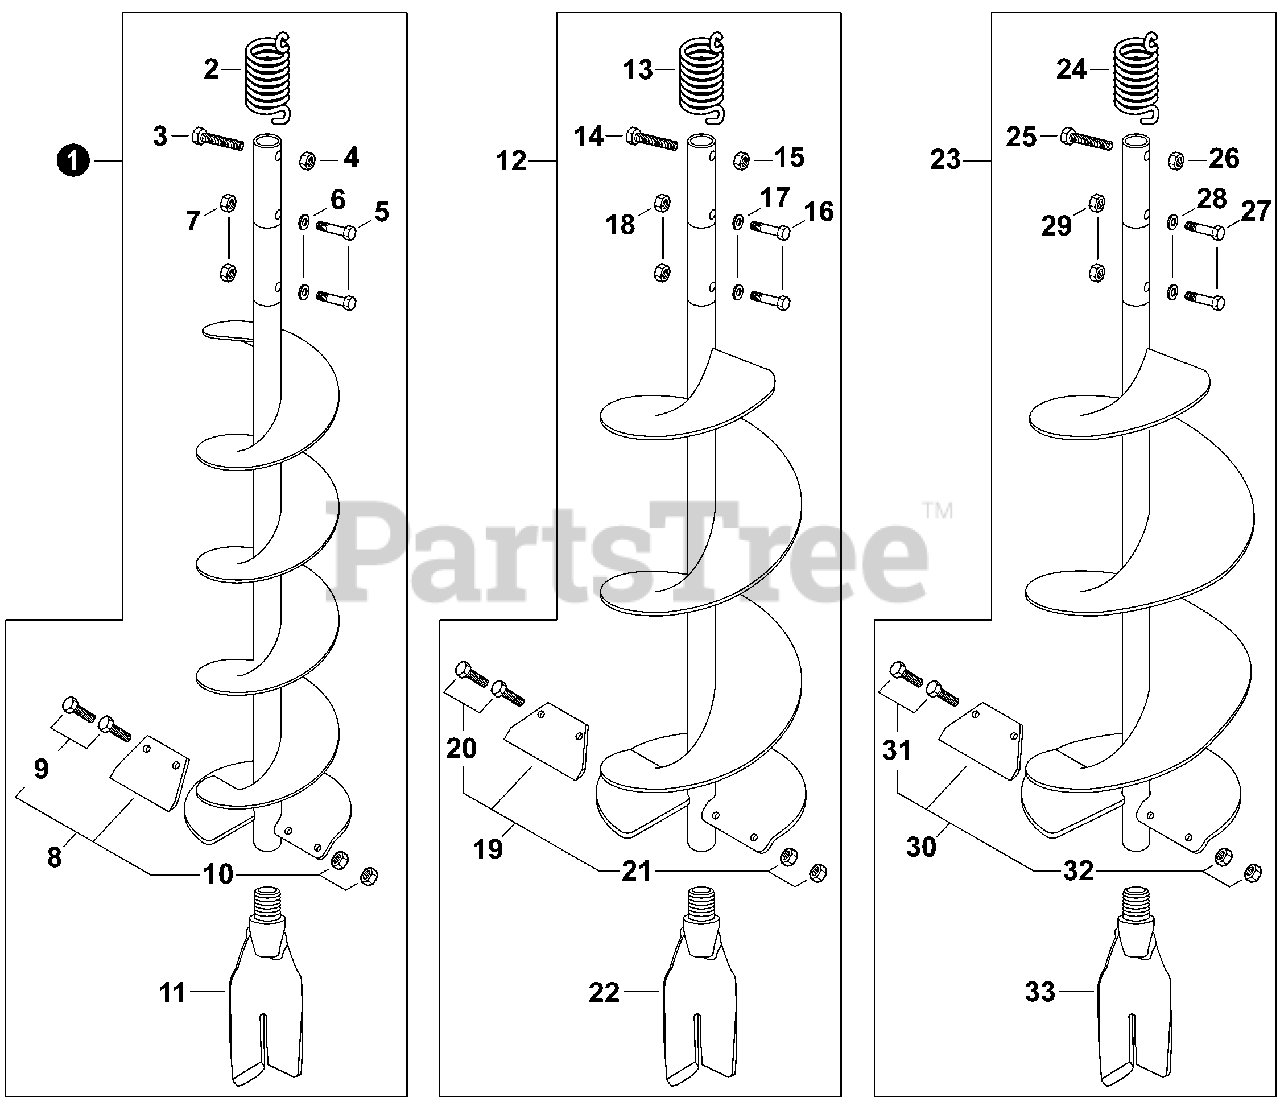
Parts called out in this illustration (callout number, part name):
1	EARTH AUGER W/POINT & SPRING - 6" DIA.
2	SPRING, TENSION
8	EARTH AUGER BLADE KIT - 6" DIA.
11	EARTH AUGER POINT - 2" DIA.
12	EARTH AUGER W/POINT & SPRING - 8" DIA.
13	SPRING, TENSION
19	EARTH AUGER BLADE KIT - 8" DIA.
22	EARTH AUGER POINT - 2" DIA.
23	EARTH AUGER W/POINT & SPRING - 10" DIA.
24	SPRING, TENSION
30	EARTH AUGER BLADE KIT - 10" DIA.
33	EARTH AUGER POINT - 2" DIA.
